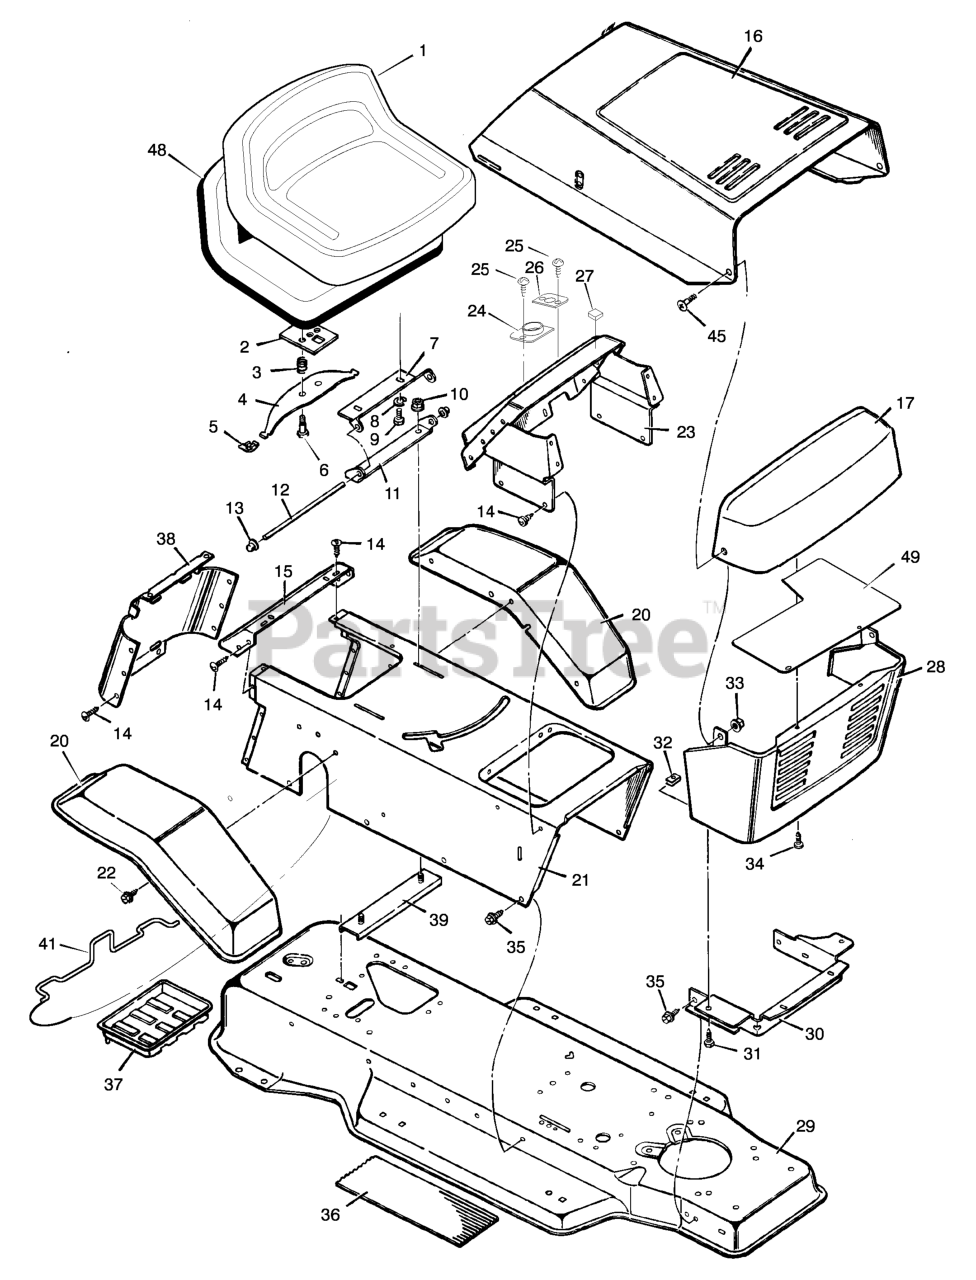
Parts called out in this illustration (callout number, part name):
2	Plate Assembly, Switch
3	Spring, Compression
4	Spring, Seat
5	Glide, Spring
6	Bolt, Shoulder
7	Support, Seat
8	Lockwasher
9	Bolt, Hex
10	Locknut, Flange
11	Bracket, Pivot
12	Rod, Pivot
13	Cap, Push On
14	Screw, Tap
15	Fender, Apron
17	Grille, Upper
21	Console Assembly
23	Dash Panel
24	Bearing, Steering
26	Bearing
27	Bumper
28	Grill, Lower
29	Frame Assembly
30	Support, Grill
32	U- Nut
33	Locknut, Flange
34	Fastener, Plastic
37	Tray, Battery
38	Cap, Console
39	Channel Assembly
41	Clamp, Battery
45	Bolt, Shoulder
48	Pan, Seat (with foam)
49	Shield, Heat
